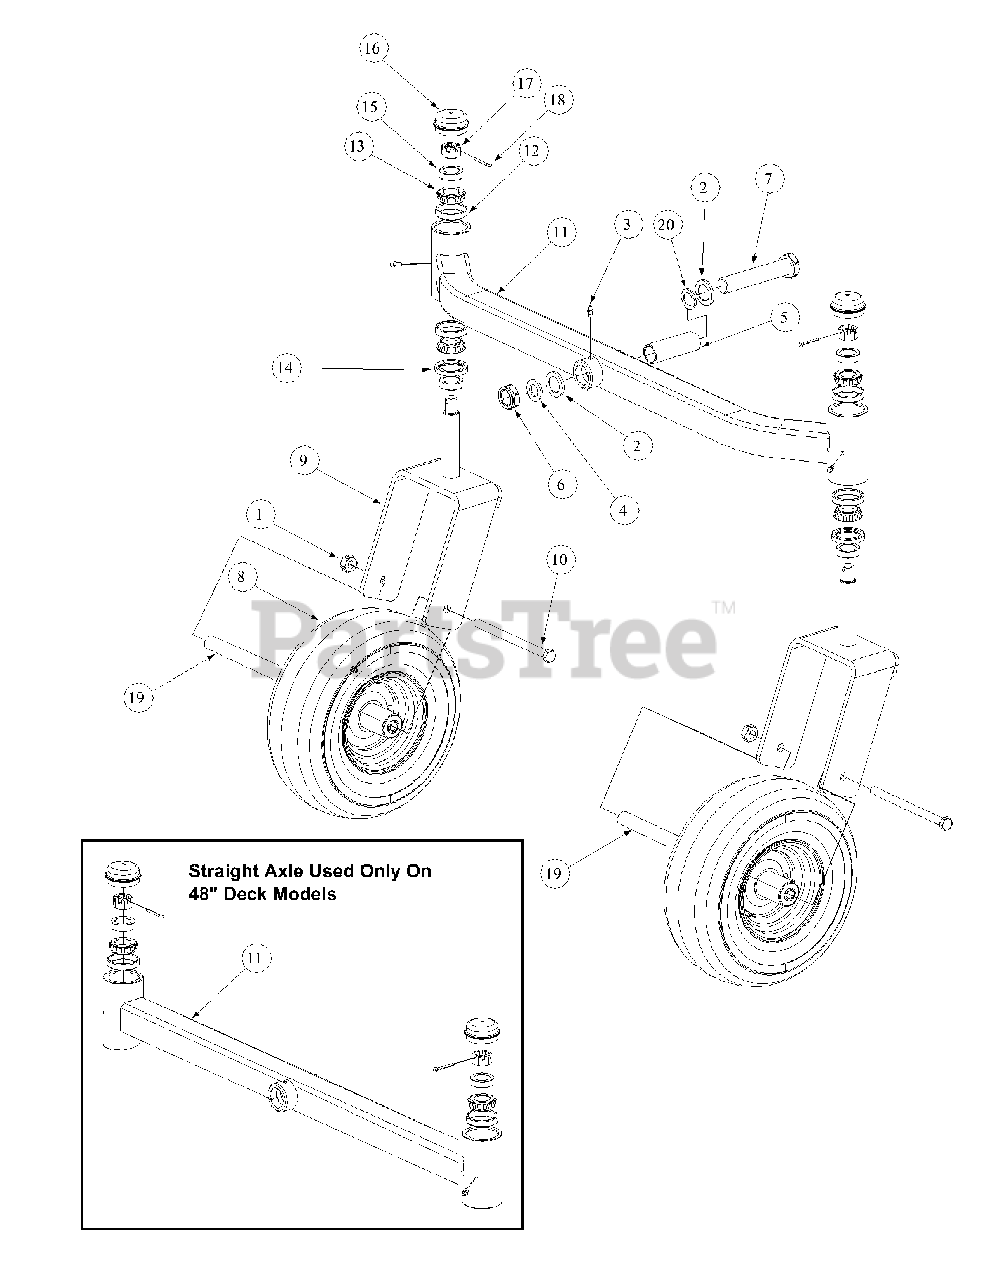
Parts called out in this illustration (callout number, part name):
1	Nut, 1/2-20, Center Lock
2	Bell Washer, 1.25 ID
3	Grease Fitting
4	Special Washer
5	Spacer, 1.005 ID x 1.25 OD x 3.6
6	Nut, Jam, 1.0-14, Insert Lock
7	Hex Cap Screw, 1-14 x 5.0
8	Wheel, 13 x 5-6, White: Includes;
8	Front Roller Bearings
8	Front Retainer Bushings
9	Yoke, Caster Wheel
10	HHCS, 1/2-20, 7.00
11	Front Axle Assembly
11	Straight Front Axle, For 48" Only
12	Cup Bearing
13	Bearing Cone
14	Seal
15	Ring Seal
16	Grease Cap, 1.986 OD
17	Slotted Nut, 3/4-16
18	Cotter Pin, 5/32, 1.25
19	Wheel Spacer
20	Flat Washer, 1.25 ID
